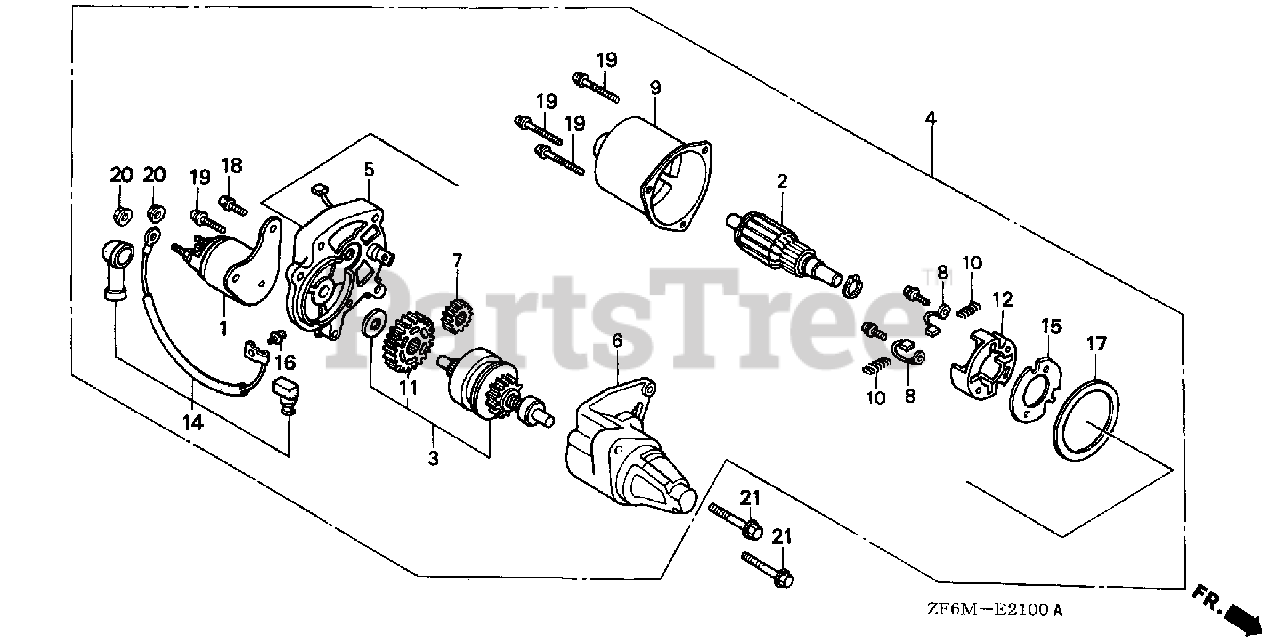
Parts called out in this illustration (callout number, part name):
1	CONTACTOR ASSY.
2	ARMATURE
3	CLUTCH, OVERRUNNING
4	MOTOR UNIT, STARTER
5	BRACKET, CENTER
6	BRACKET, FR.
7	GEAR, DRIVE PINION
8	BRUSH
9	YOKE
10	SPRING, BRUSH RETURN
11	GEAR, REDUCTION
12	HOLDER, BRUSH
14	WIRE, WATER COVER
15	INSULATOR
16	SCREW-WASHER (4X6)
17	GASKET
18	BOLT-WASHER (5X14)
19	SCREW-WASHER (5X3)
20	NUT-WASHER (6MM)
21	BOLT, FLANGE (8X35)
